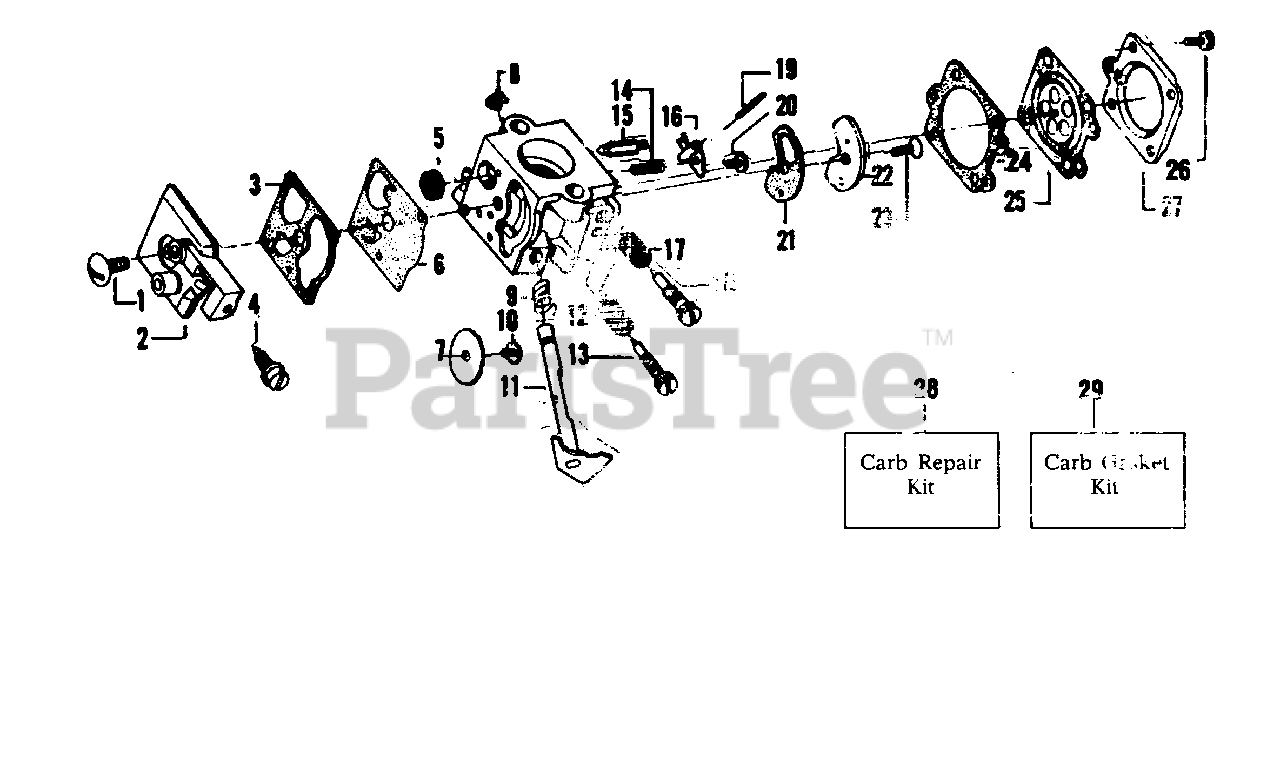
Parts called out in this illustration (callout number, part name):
1	Pump Cover Screw
2	Pump Cover Ass'y. (Inc.4)
3	Pump Gasket
4	Idle Adjustment Screw
5	Inlet Screen
6	Diaphragm Pump
7	Throttle Valve
8	Throttle Shaft Clip
9	Throttle Return Spring
10	Throttle Valve Screw
11	Shaft Ass'y. - Throttle
12	Idle Needle Spring
13	Idle Needle
14	Metering Lever Spring
15	Inlet Needle Valve
16	Metering Lever
17	Hi Speed Needle Spring
18	Hi Speed Needle
19	Metering Lever Pin
20	Metering Lever Pin Screw
21	Circuit Plate Gasket
22	Circuit Plate
23	Circuit Plate Screw
24	Metering Diaphragm Gasket
25	Metering Diaphragm Ass'y.
26	Metering Cover & Throttle Shaft Clip Ass'y. Screw
27	Metering Diaphragm Cover
28	Carb Kwik Repair Kit
29	Carb. Gasket/Diaphragm Kit
